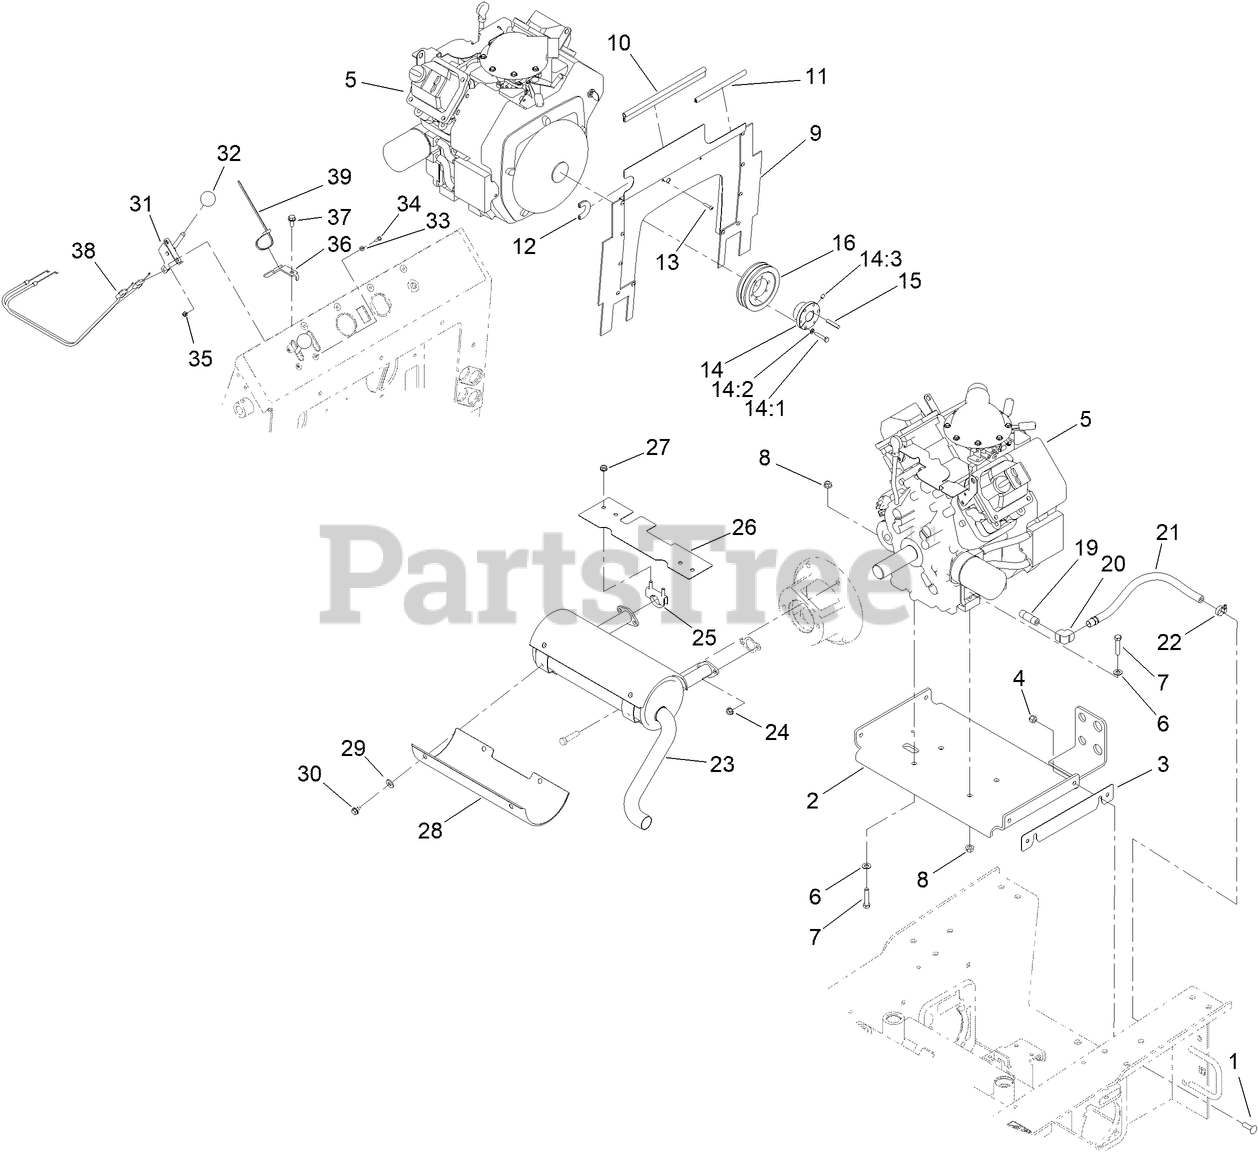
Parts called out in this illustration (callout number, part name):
1	SCREW-CARR
2	PLATE-MOUNTING, ENGINE
3	SHIM-STRAP
4	NUT-LOCK, NI
6	WASHER-PLAIN
7	SCREW-HH
8	NUT-HF
9	BAFFLE-ENGINE
10	STRIP-SEAL, 10.5 INCH
11	SEAL-STRIP, 6.5 INCH
12	SEAL-STRIP, 3 INCH
13	SCREW-PPH
14	BUSHING
14:1	SCREW-HH
14:2	WASHER-LOCK
14:3	SCREW-SET, HSH
15	KEY-SQUARE
16	PULLEY
19	NIPPLE
20	ELBOW-90 DEG
21	OIL HOSE ASM
22	CLAMP-HOSE
23	MUFFLER
24	NUT-HF
25	Clamp-Muffler
26	SHIELD-MANIFOLD
27	NUT-HF
28	SHIELD-MUFFLER
29	WASHER-FLAT
30	SCREW
31	LEVER-CONTROL
33	WASHER-FLAT
35	NUT-KEPS
36	GUIDE-CABLE
37	SCREW-THD ROLL, HWH
38	CABLE-THROTTLE/CHOKE
39	TIE-CABLE
